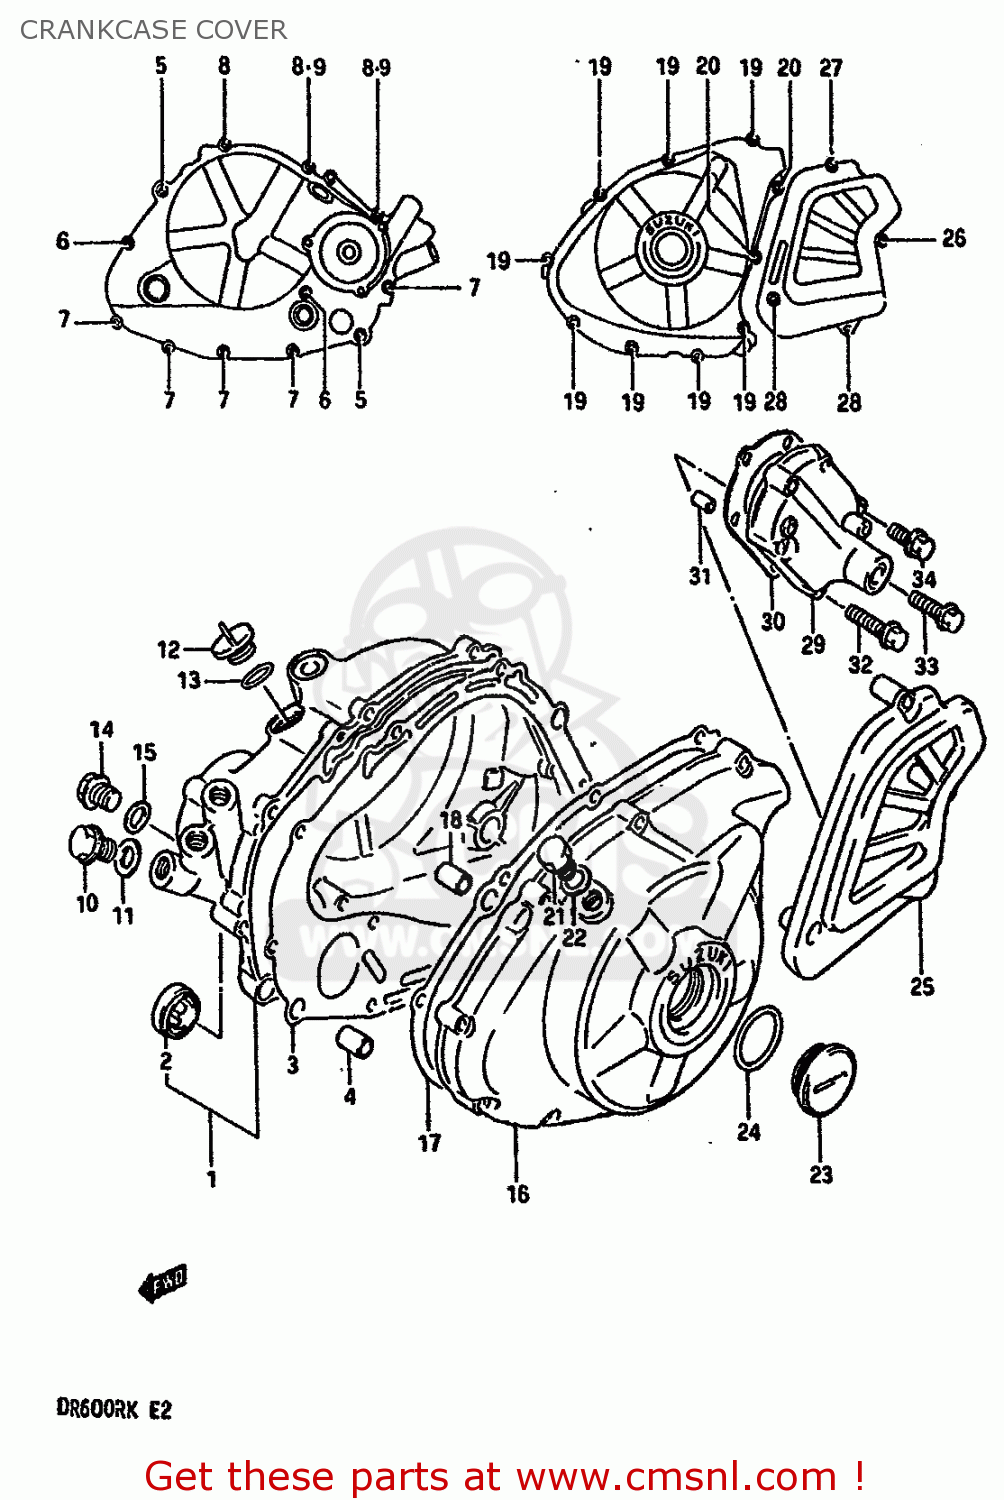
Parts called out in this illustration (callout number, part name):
1	COVER,CLUTCH
2	LENS,OIL LEVEL CHECK
3	GASKET,CLUTCH COVER
4	PIN
5	BOLT 6X50
6	BOLT 6X40
7	BOLT 6X35
8	BOLT 6X25
9	GASKET(5.8X13X1.2) (NAS)
10	PLUG(14X12)
11	GASKET(14X19.2X2) (NAS)
12	PLUG
13	O RING(D:3.1,ID:16.8)
14	PLUG(14X12)
15	GASKET(14X19.2X2) (NAS)
16	COVER,MAGNETO
17	GASKET,MAGNETO COVER (MCA)
18	PIN
19	BOLT 6X30
20	BOLT 6X25
21	PLUG(12X9)
22	GASKET(12.1X16.2X3.7) (NAS)
23	PLUG
24	O RING(D:3.1,ID:32.7)
25	COVER,ENGINE SPROCKET
26	BOLT
27	BOLT 6X35
28	BOLT 6X20
29	COVER,GEAR SHIFT
30	GASKET,GEAR SHIFT COVER (MCA)
31	PIN
32	BOLT 6X35
33	BOLT 6X30
34	BOLT 6X20
